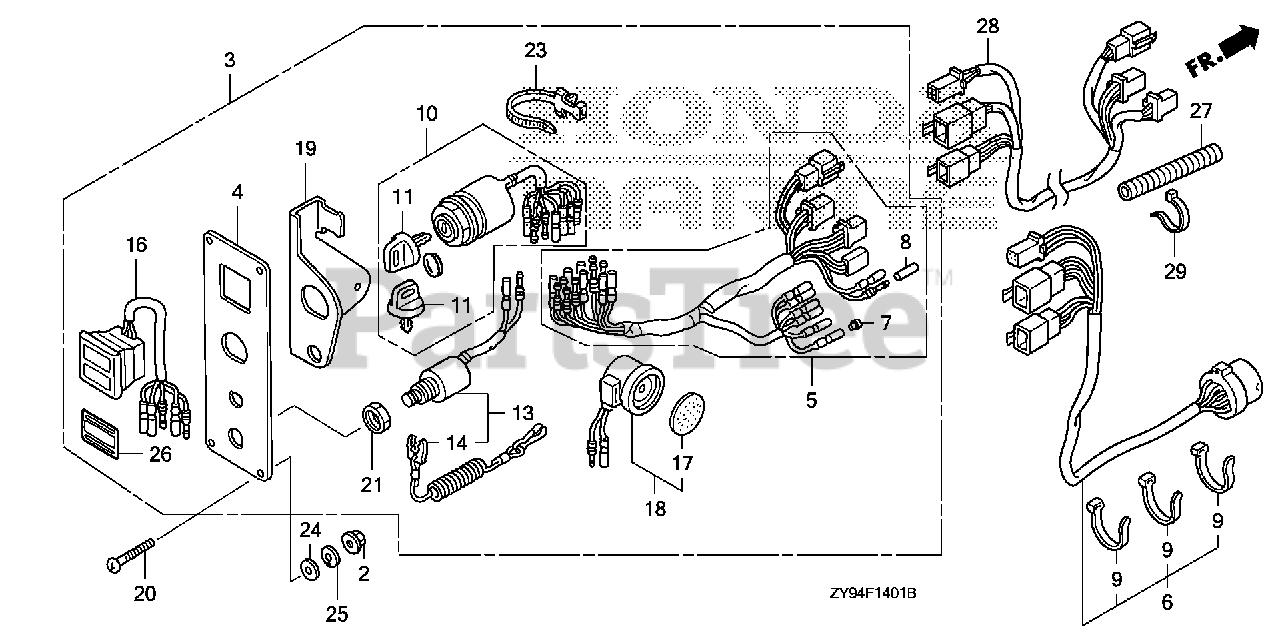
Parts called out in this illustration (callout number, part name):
2	NUT, FLANGE (5MM)
3	PANEL ASSY., CONTROL (2-LED)
4	PANEL, CONTROL
5	HARNESS ASSY., SWITCH PANEL
6	CABLE ASSY., SWITCH PANEL
7	PLUG, CONNECTOR (INNER)
8	PLUG, CONNECTOR (OUTER)
9	TIE, CABLE (2.4X92) (NATURAL)
10	SWITCH ASSY., COMBINATION
11	KEY ASSY., COMBINATION SWITCH (35100-ZV5-003 ONLY)
13	SWITCH ASSY., EMERGENCY STOP
14	WIRE, EMERGENCY
16	LAMP ASSY., INDICATION (2-LED)
17	PLATE, TURN SIGNAL BUZZER
18	BUZZER, WARNING
19	BRACKET, BUZZER
20	SCREW, PAN (5X40)
21	NUT, HEX. (16MM)
23	BAND, WIRE HARNESS (150MM) (NATURAL)
24	WASHER, PLAIN (5MM)
25	WASHER, SPRING (5MM)
26	MARK, SWITCH PANEL
27	TUBE, CORRUGATE (28MM)
28	CABLE ASSY., REMOTE CONTROL EXTENSION
29	BAND, SELF-LOCK
